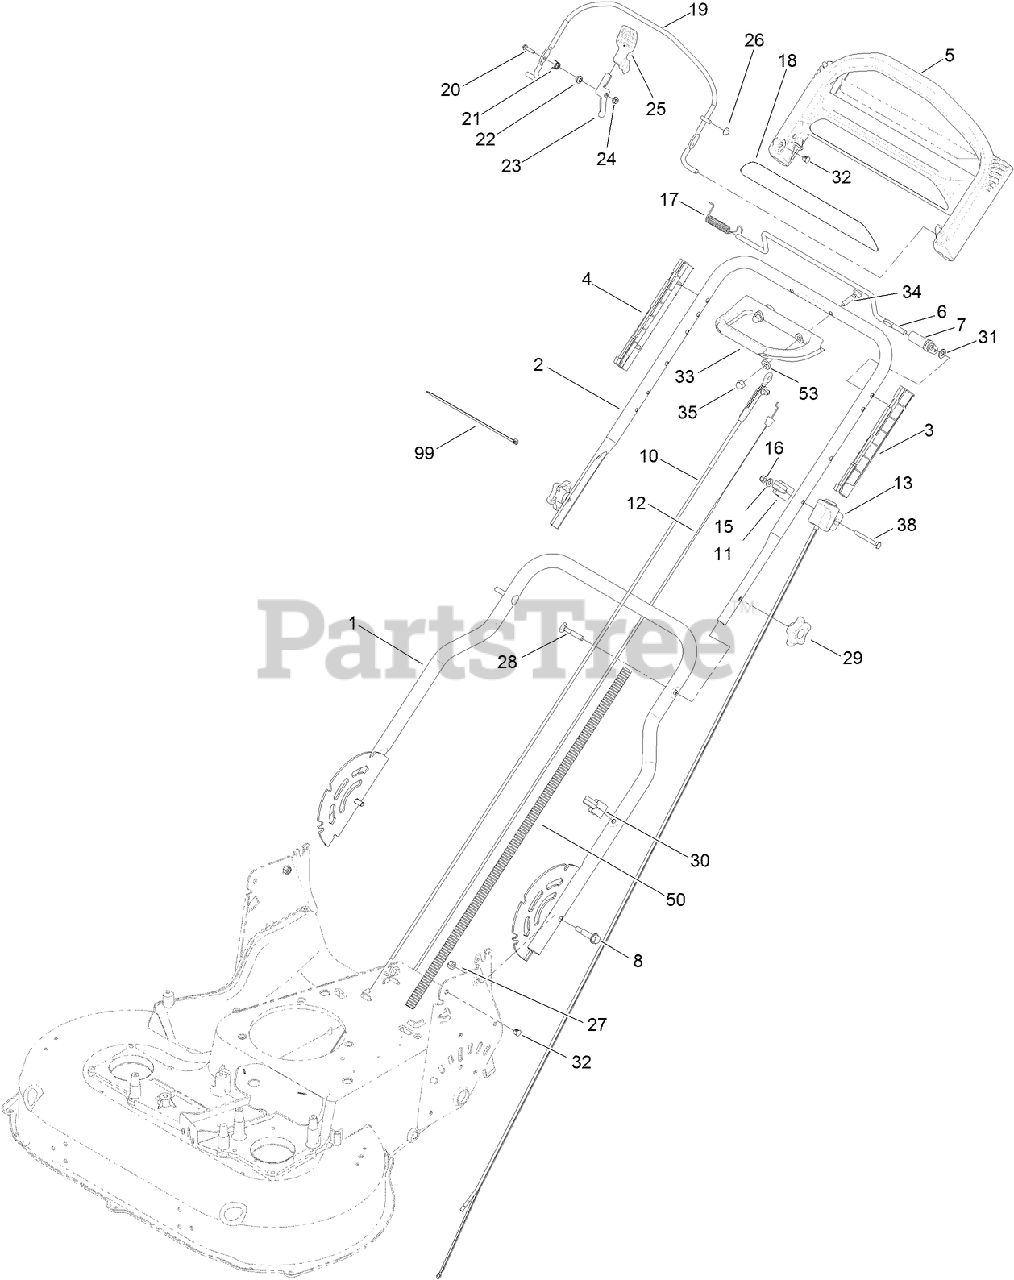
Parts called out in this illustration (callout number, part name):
1	HANDLE-LOWER
2	HANDLE-UPPER
3	GUIDE-LH
4	GUIDE-RH
5	HANDLE-CONTROL
7	LEVER-TRACTION
8	BOLT-SHOULDER, HHF
12	CABLE-TRACTION
13	SWITCH HOUSING ASM
15	WASHER-FLAT
16	NUT-LOCK, NI
18	DECAL-HANDLE
19	BAIL-BRAKE
20	SCREW-HWH
21	SPRING-TORSION
22	SPACER
23	LEVER
24	NUT-LOCK, FLANGE
26	NUT-SPEED
27	NUT-LOCK, NI
28	SCREW-HANDLE
29	KNOB-HANDLE
30	GUIDE-CABLE
31	WASHER-PLAIN
32	PLUG-DOME
33	HANDLE-ASSIST, TRACTION
34	SCREW-HANDLE, LOCK
35	NUT-ACORN
38	SCREW-HH
50	CONDUIT-CONVOLUTED
53	WASHER-PLAIN
99	TIE-CABLE
